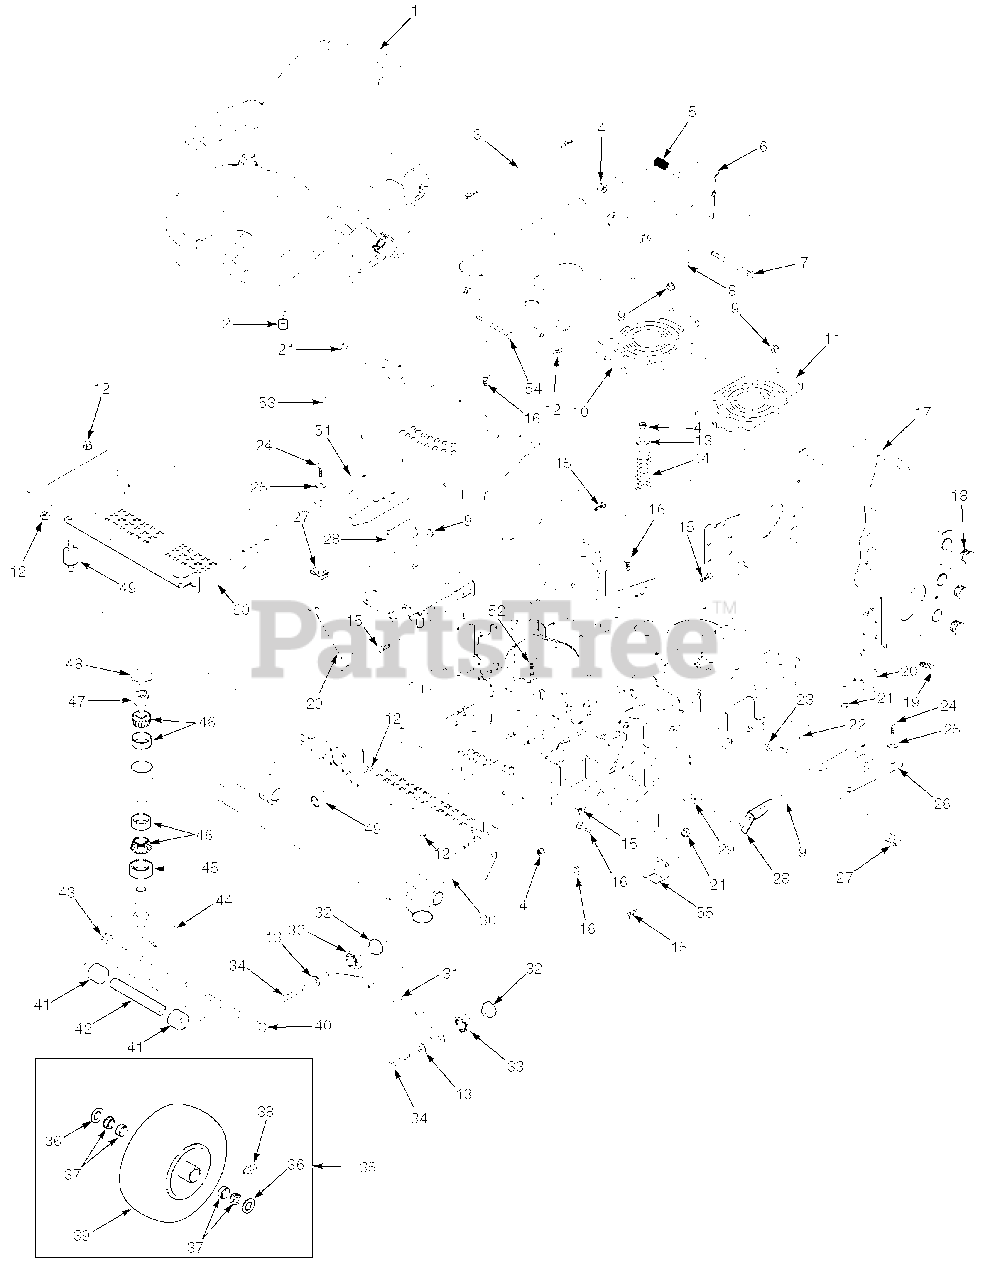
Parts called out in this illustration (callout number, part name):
1	Seat Assembly
2	Spacer
3	Cable, Seat Stop
4	Nut, Elastic Stop 3/8-16
5	Spring, Seat Latch
6	Weldment, Seat Latch
7	Bolt, Hex Head 3/8-16 x 6"
8	Seat Plate Weldment, SFZ 61
9	Nut, Serrated Flange 1/4-20
10	Fan Cover, RH
11	Fan Cover, LH
12	Nut, Serrated Flange 5/16-18
13	Flatwasher, 3/8-.391 x .938 x .105
14	Spring, Seat
15	Bolt, Carriage 1/4-20 x 1"
16	Bolt, Carriage 5/16-18 x 3/4"
17	Bumper Weldment
18	Plug, Bumper Tube
19	Bolt, Hex Head 3/8-16 x 1"
20	Anti-Rotation Bracket
21	Nut, Elastic Stop 5/16-18
22	Bracket, Dump Valve
23	Nut, Serrated Flange 3/8-16
24	Bolt, Hex Head 1/4-20 x 1"
25	Flatwasher, 1/4-.312 x .750 x .065
26	Control Plate w/Decal, LH
27	U-Nut, 1/4-20
28	Bracket, Switch Mount
29	Bracket, Tank Mount
30	Mainframe Assy., w/Decals
31	Support, Deck Guide
32	Spacer, Bearing
33	Bearing
34	Bolt, Hex Head 3/8-16 x 2-1/2"
35	Wheel Assembly
37	Bearing
38	Fitting, Grease
39	Tire, 13 x 5-6
40	Bolt, Hex Head 1/2-13 x 7-1/2"
41	Spacer, Caster Wheel
42	Sleeve, Caster Wheel
43	Nut, Elastic Stop 1/2-13
44	Yoke Weldment
45	Seal, 2" OD x 1.625 ID
46	Bearing Set
47	Nut, Elastic Stop 1"-14
48	Grease Cap
49	Rubber Isolator
50	Footplate Weldment
51	Control PLate w/Decal, RH
52	Bolt, Carriage 3/8-16 x 1-1/4"
53	Deck Lift Cover w/Decal
54	Bolt, Hex Head 5/16-18 x 3-3/4"
55	Switch Bracket
